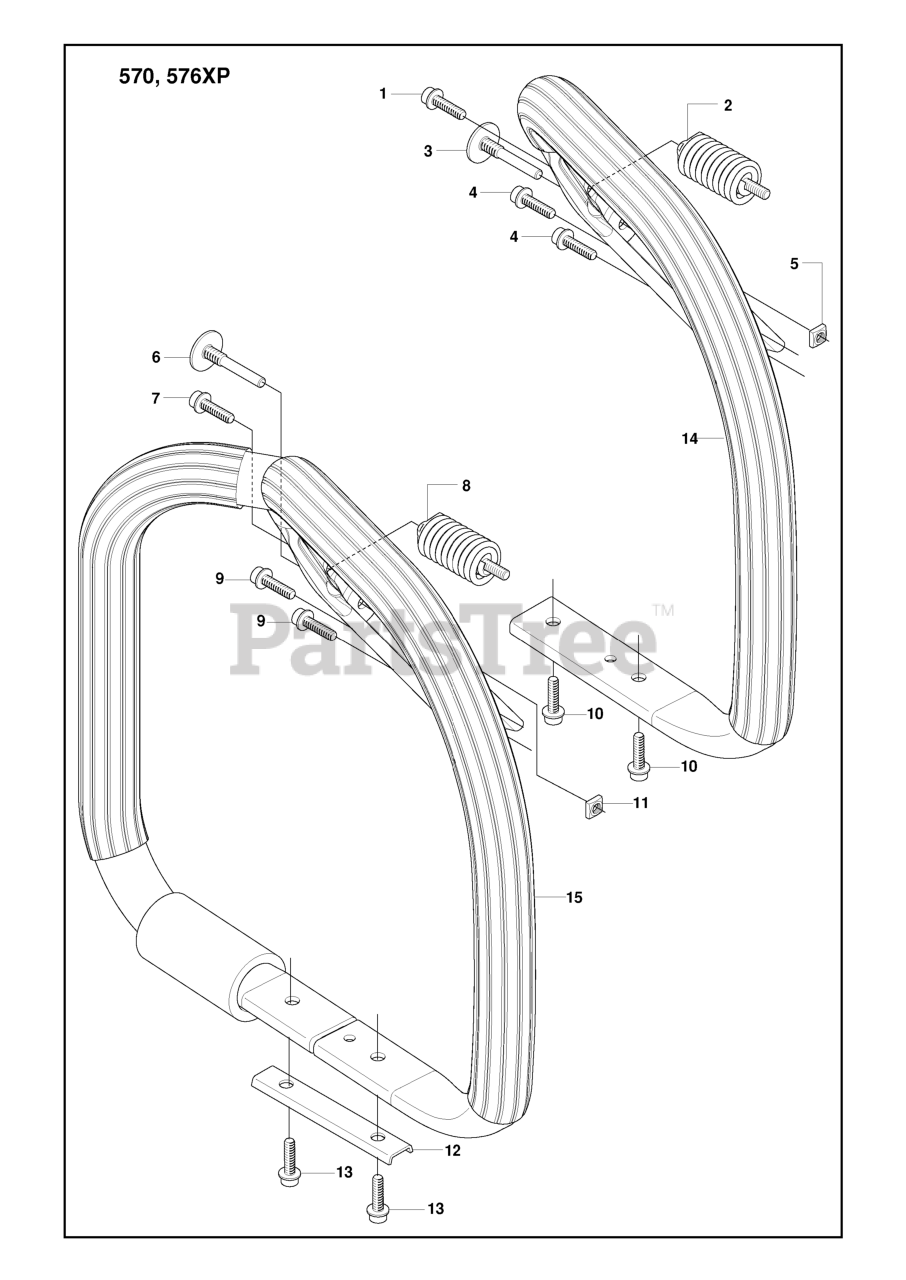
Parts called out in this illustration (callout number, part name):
2	ANTIVIBE MOUNT
8	ANTIVIBE MOUNT
14	%FRONT HANDLE
14	FRONT HANDLE ASSY
15	HANDLE
